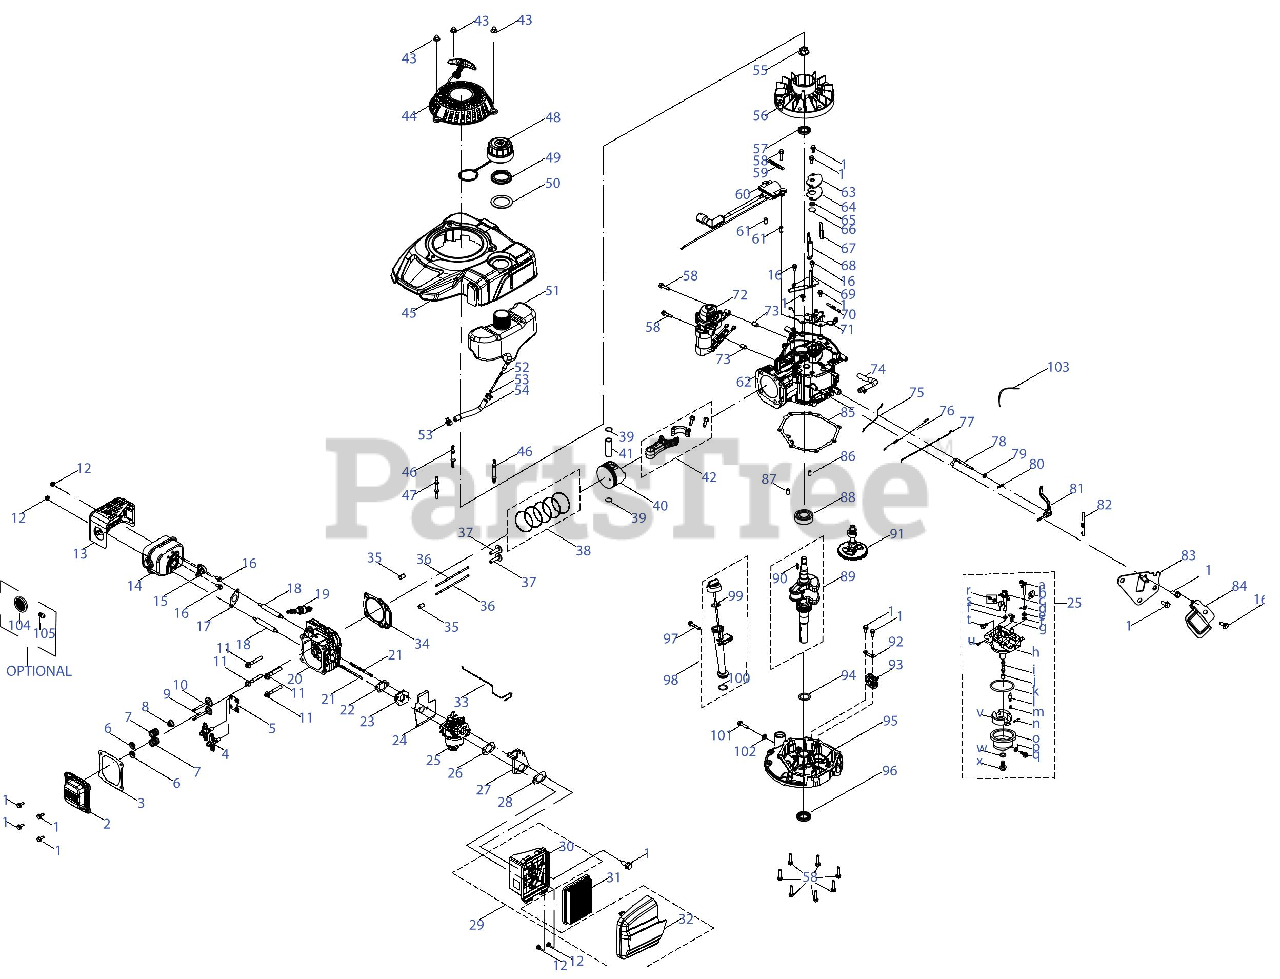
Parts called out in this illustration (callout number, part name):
1	Bolt M6x14
2	Valve Cover
3	Valve Cover Gasket
4	Rocker Arm Assembly
5	Push Rod Guide
6	Valve Spring Retainer
7	Valve Spring
8	Intake Valve Seal
9	Exhaust Valve
10	Intake Valve
11	Bolt M8x54 Cylinder Head
13	Muffler Shield
14	Muffler Assembly
15	Choke Thermal Control
16	Bolt M6x12
17	Muffler Gasket
18	Muffler Stud M6x95
19	Spark Plug/F5RTC
20	Cylinder Head
21	Carb Stud M6x87
22	Carburetor Insulator Gasket
23	Carburetor Insulator
24	Carburetor Gasket
25	Carburetor Assembly
26	Air Filter Bracket Gasket
27	Air Filter Bracket
28	Air Filter Base Gasket
29	Air Filter Assembly
30	Air Filter Base
31	Air Filter Element, Paper
32	Air Filter Cover
33	Temp Control Linkage
34	Cylinder Head Gasket
35	Cylinder Head Dowel Pin 10x16
37	Tappet
38	Piston Ring Set
39	Piston Pin Snap Ring
41	Piston Pin
42	Connecting Rod Assembly
43	Starter Acorn Nut
44	Starter Recoil Assembly
45	Engine Shroud Assembly
46	Shroud Stud M6x78.5
47	Shroud Stud M6x74
48	Fuel Cap Assembly
49	Fuel Tank Nut
50	Fuel Tank Upper Grommet
51	Fuel Tank
52	Fuel Filter
53	Fuel Hose Clamp
54	Fuel Hose
55	Flywheel Nut M14
57	Upper Crankshaft Seal
58	Bolt M6x28
59	Flexible Clamp
60	Ignition Coil Assembly
61	Ignition Coil Spacer
63	Breather Cover Plate
64	Breather Gasket
65	Breather Valve Spring
66	Breather Valve
67	Breather Screen
68	Air Vane
69	Air Vane Bracket
70	Brake Spring
71	Brake Assembly
72	Electric Starter Assembly (69:12)
73	Starter Housing Dowel Pin 8x8
74	Breather Hose Assembly
75	Choke Linkage
76	Throttle Linkage Spring
77	Throttle Linkage
78	Governor Arm Shaft
79	Governor Seal
80	Governor Arm Shaft Cotter Pin
81	Governor Arm Assembly
82	Governor Spring
83	Component Bracket
84	Governor Shield
85	Crankcase Cover Gasket
86	Crankcase Cover Dowel Pin 7x14
87	Crankcase Cover Dowel Pin 9x14
88	Main Bearing
89	Crankshaft Assembly
90	Flywheel Key
91	Camshaft Assembly
92	Governor Gear Mounting Plate
93	Governor Gear/Shaft Assembly
94	Crankshaft Thrust Washer
95	Crankcase Cover
96	Lower Crankshaft Seal
97	Bolt M6x35
98	Dipstick Assembly
99	Dipstick / Oil Fill Tube O-Ring
100	Dipstick / Oil Fill Tube O-Ring
101	Oil Drain Plug
102	Oil Drain Plug Washer
103	Plastic Tie 150Mm
104	Spark Arrestor
105	Spark Arrestor Screw
